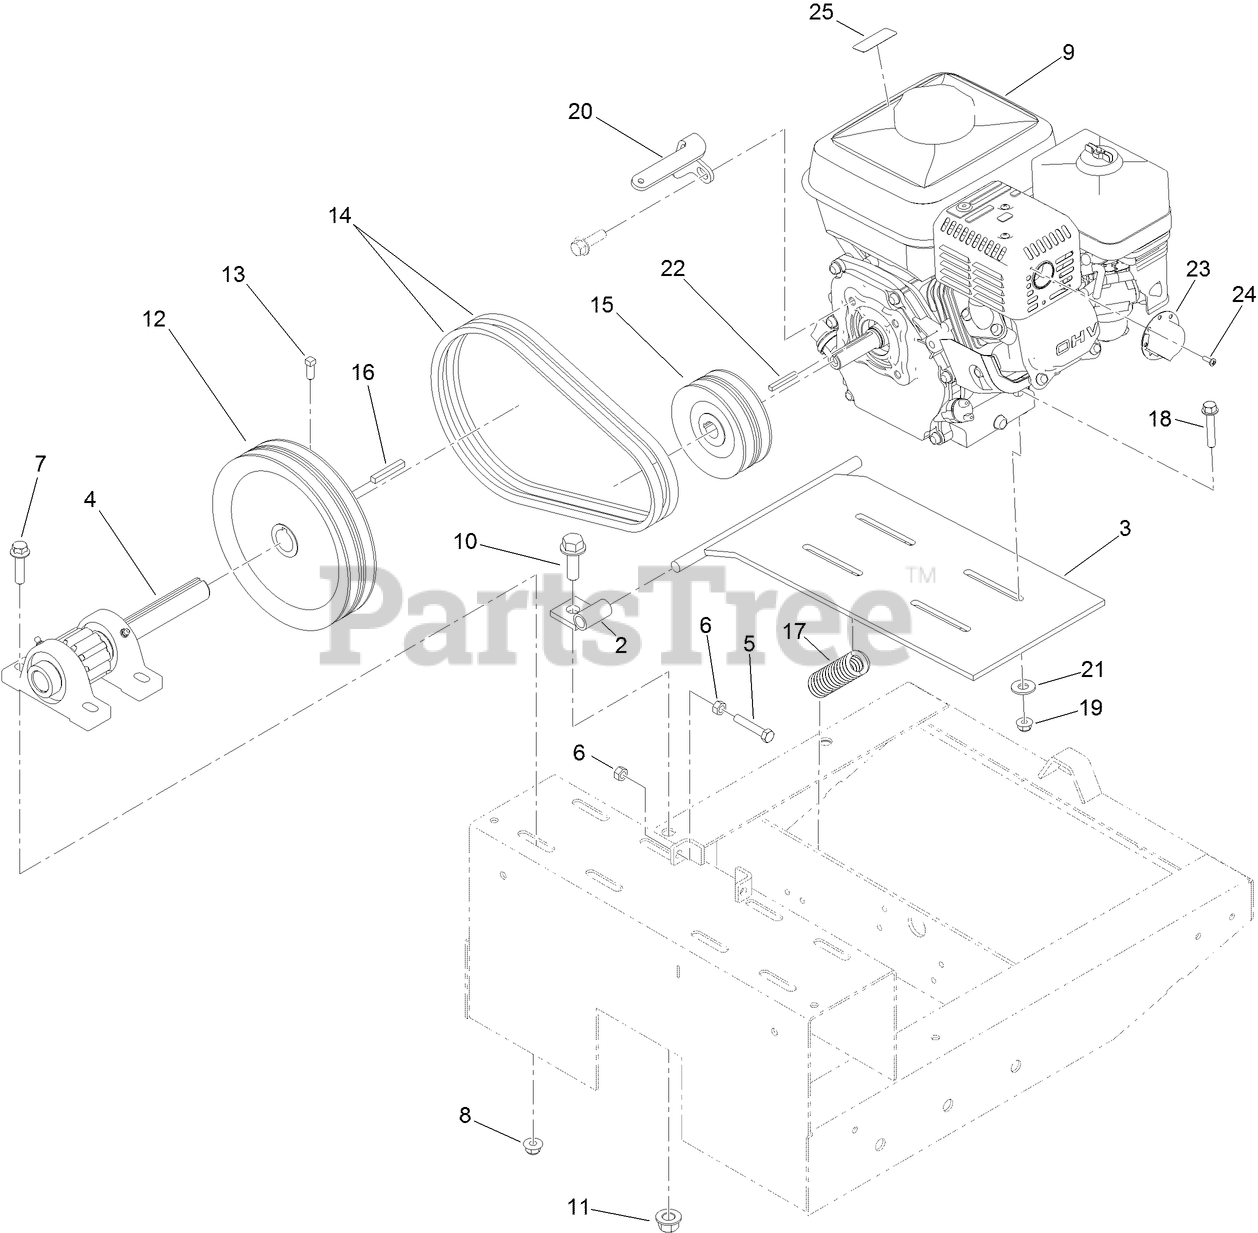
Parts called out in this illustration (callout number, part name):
2	MOUNT-MOTOR
3	BASE-MOTOR
4	PINION ASM
5	SCREW-HH
6	NUT-HEX
7	SCREW-HHF
8	NUT-HF, NI
9	ENGINE-HONDA, GX160
10	SCREW-HHF
11	NUT-LOCK
12	SHEAVE
13	SCREW-SET, SQH
14	BELT-V
15	SHEAVE
16	KEY-SQUARE
17	SPRING
18	SCREW-HWH
19	NUT-HF, NI
20	GUIDE-BELT
21	WASHER-FLAT
22	KEY-SQUARE
23	DEFLECTOR
24	SCREW-TAP
25	DECAL-WARNING, ETHANOL
